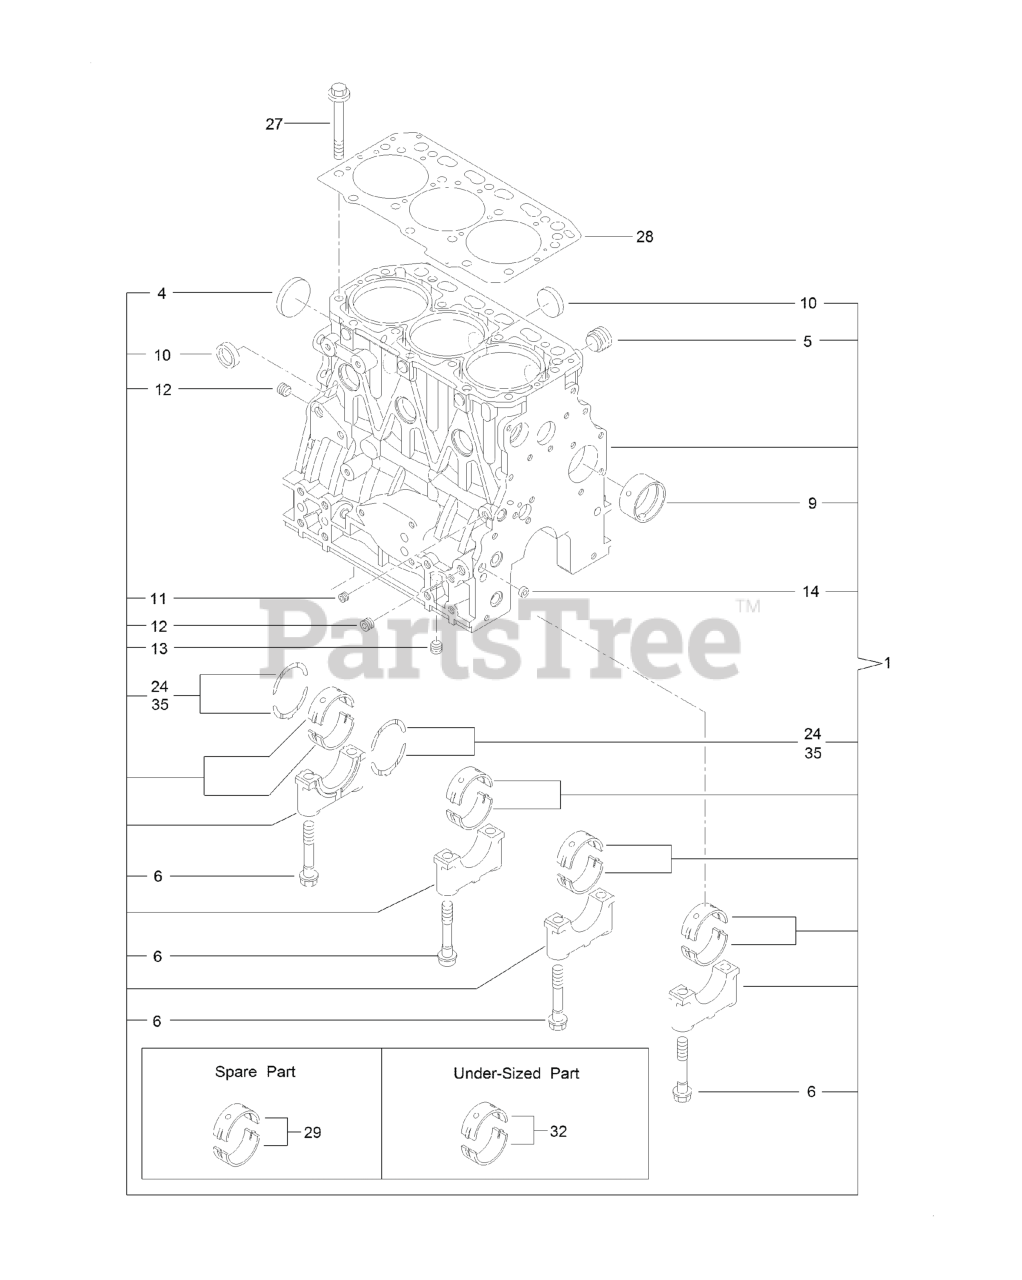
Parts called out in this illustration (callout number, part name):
1	CYLINDER BLOCK ASM
9	BUSHING
24	METAL-THRUST
28	HEAD GASKET ASM
29	METAL-MAIN
32	METAL-MAIN (0.25)
35	METAL-THRUST (0.25)
